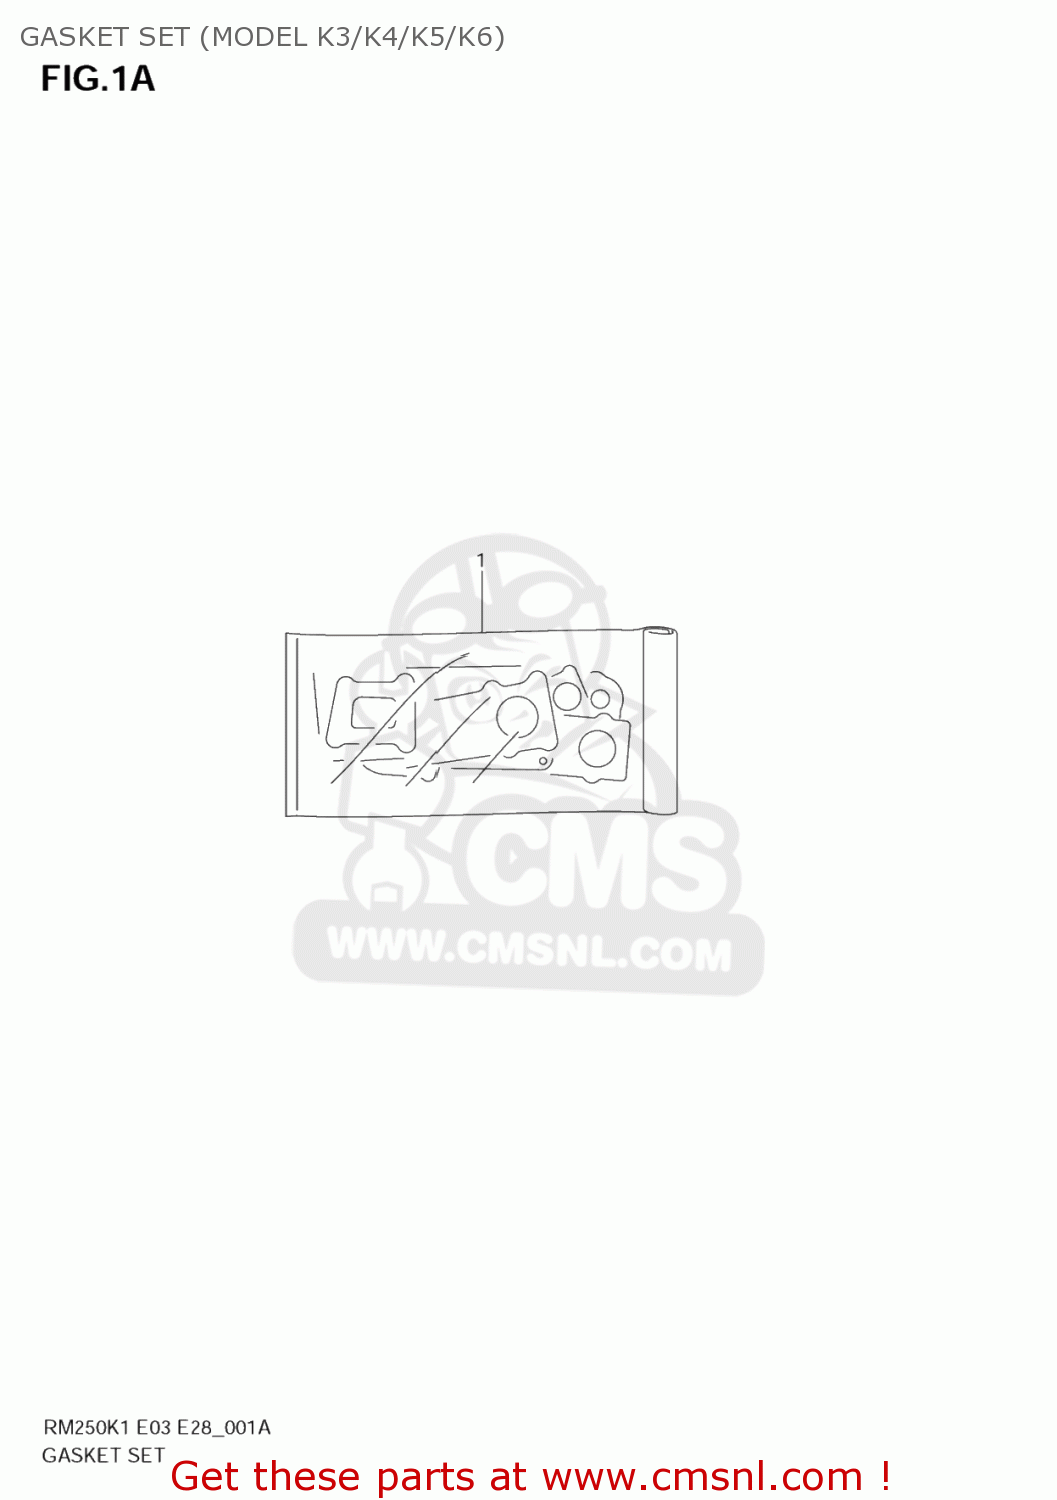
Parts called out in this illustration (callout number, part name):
1	GASKET SET (NAS)
2	O RING,CYLINDER HEAD NO.1
3	O RING,CYLINDER HEAD NO.2
4	GASKET,CYLINDER COVER NO.1 (NAS)
5	GASKET,CYLINDER COVER NO.3 (NAS)
6	GASKET,CYLINDER COVER NO.2 (NAS)
7	GASKET,CYLINDER (NAS)
8	GASKET,CRANKCASE (NAS)
9	GASKET,COVER (NAS)
10	GASKET,MAGNETO COVER
11	O RING,CL COVER OUTER
12	O RING,EXHAUST PIPE
13	WASHER,EXHAUST PIPE
